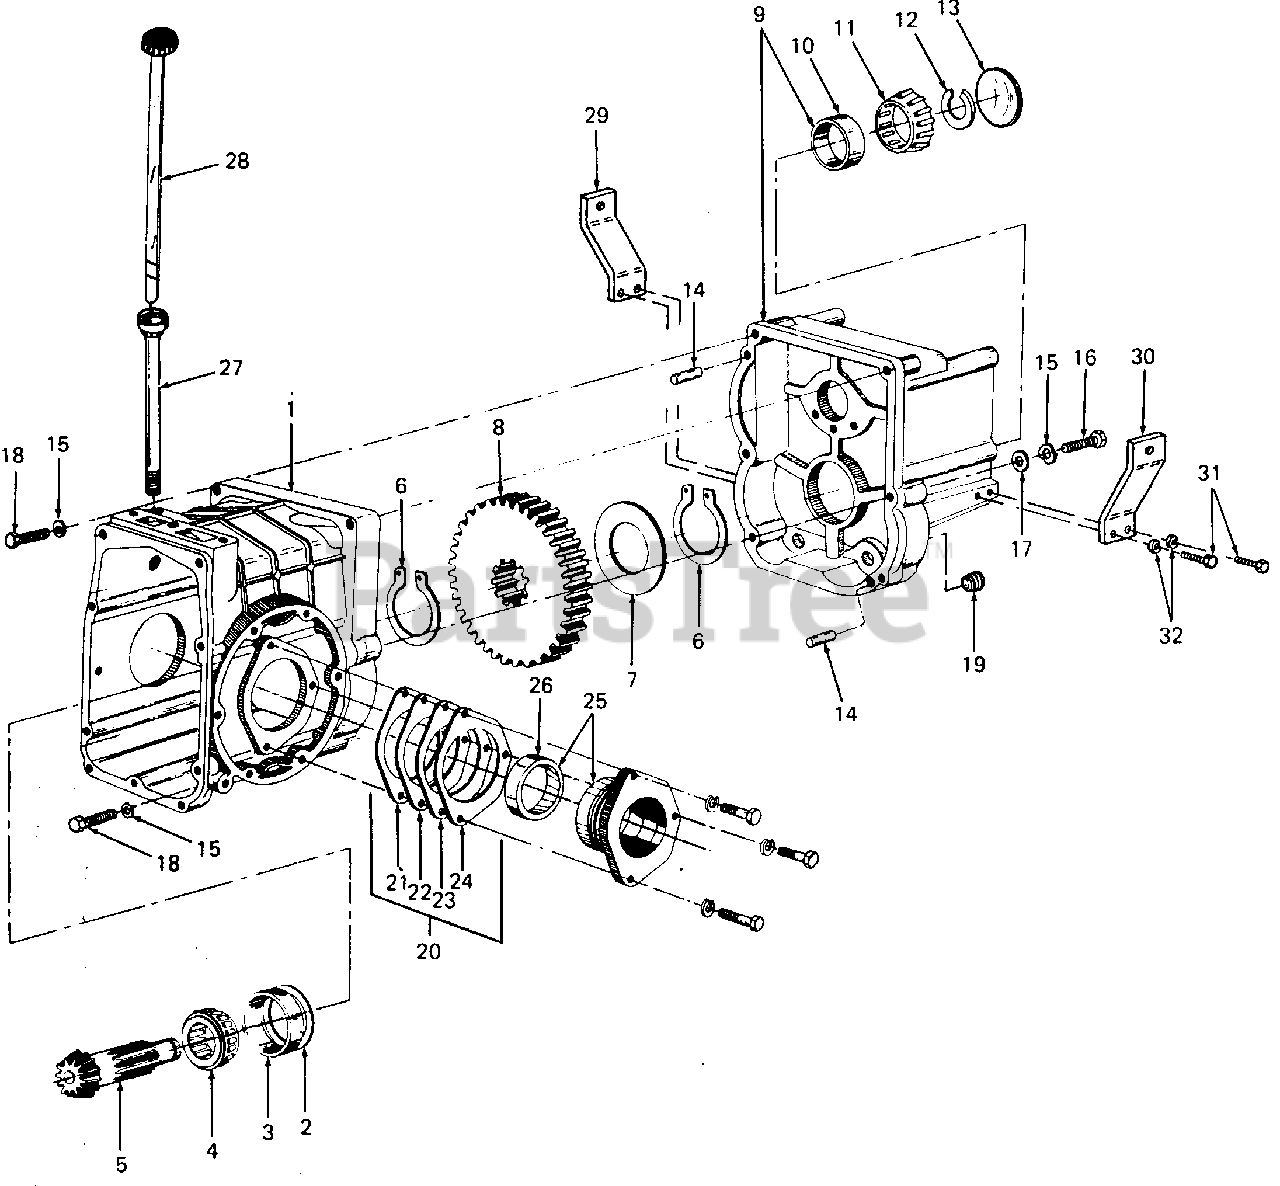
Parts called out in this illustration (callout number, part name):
1	Housing Assy, Rear Transaxle
2	Shim, Rear Bearing Cup, .004 Thk
3	Cup, Roller Bearing
4	Cone, Roller Bearing
5	Shaft, Bevel Pinion
6	Ring, Retaining, 1.312 Dia
7	Spacer, Gear
8	Gear, Reduction - 66T
9	Housing Assy, Adapter w/Cup
10	Cup, Roller Bearing
11	Cone, Roller Bearing
12	Retainer, Front Bearing, .125 Thk
13	Plug, Expansion, 2.12 OD
14	Pin, Dowel, 3/8 Dia X 5/8 Lg
15	Washer, Spring, .445 X .75 X .017 Thk
16	Screw, Hex Cap, 7/16-14 X 2.5 Lg GR5
17	Washer, Flat, .46 X .875 X .060 Thk
18	Screw, Hex Cap, 7/16-14 X 1.75 Lg GR5
19	Plug, Drain
20	Shim Package
21	Shim, Bearing Retainer, .004 Thk
22	Shim, Bearing Retainer, .007 Thk
23	Shim, Bearing Retainer, .014 Thk
24	Shim, Bearing Retainer, .028 Thk
25	Retainer Assy, Bearing w/Cup
26	Cup, Roller Bearing
27	Tube, Dipstick
28	Blade Assy, Dipstick
29	Bracket, Trans Mtg - LH
30	Bracket, Trans Mtg - RH
31	Bolt, Hex Patch, 3/8-16 X 1.0 Lg GR5
32	Washer Lock 3/8
